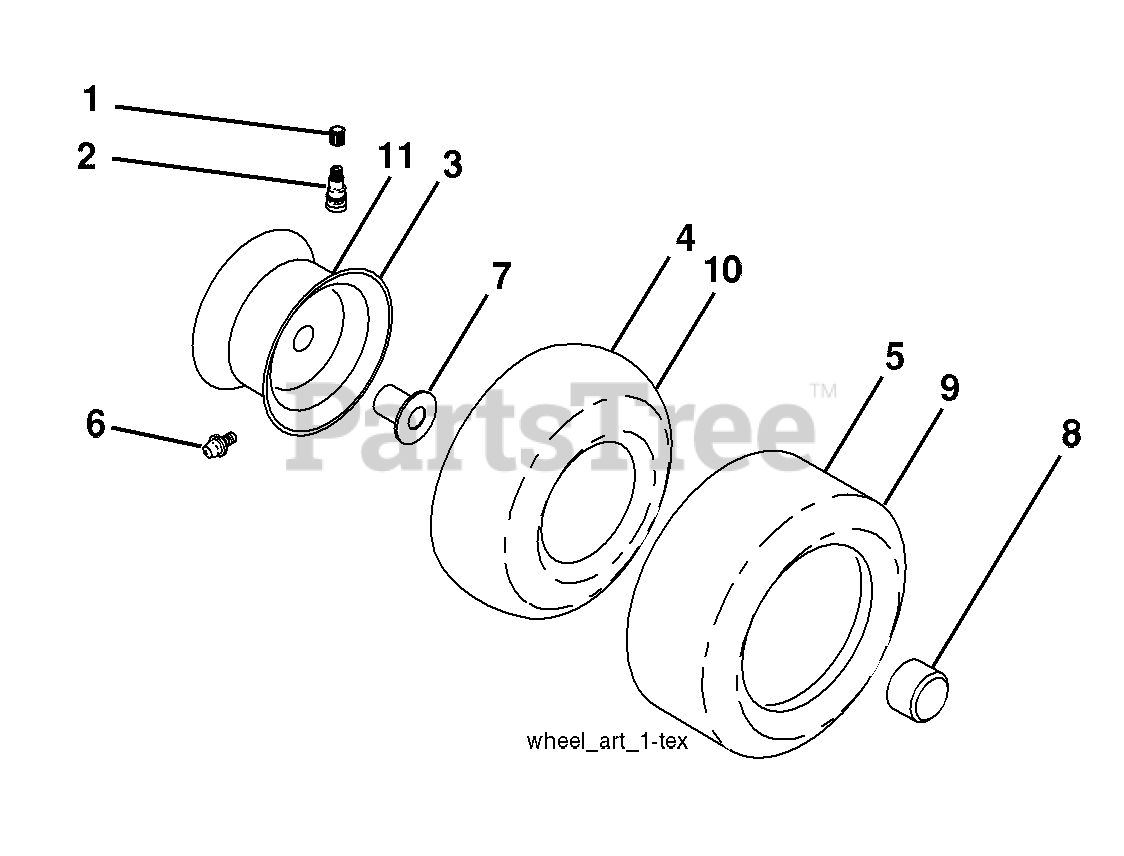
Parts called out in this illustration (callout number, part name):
1	Cap Valve Tire
2	Stem Valve
3	Rim Front Service
4	Tube Front
5	Tire Front 15 x 6.0-6 Service
6	Fitting Grease
7	Bearing Flange
8	Cap Axle Blk 1 50 x 1 00
9	Tire RT 20 x 10-8 Service
10	Tube Rear
11	Rim Asm 8" Rear Service
11	Sealant, Tire
